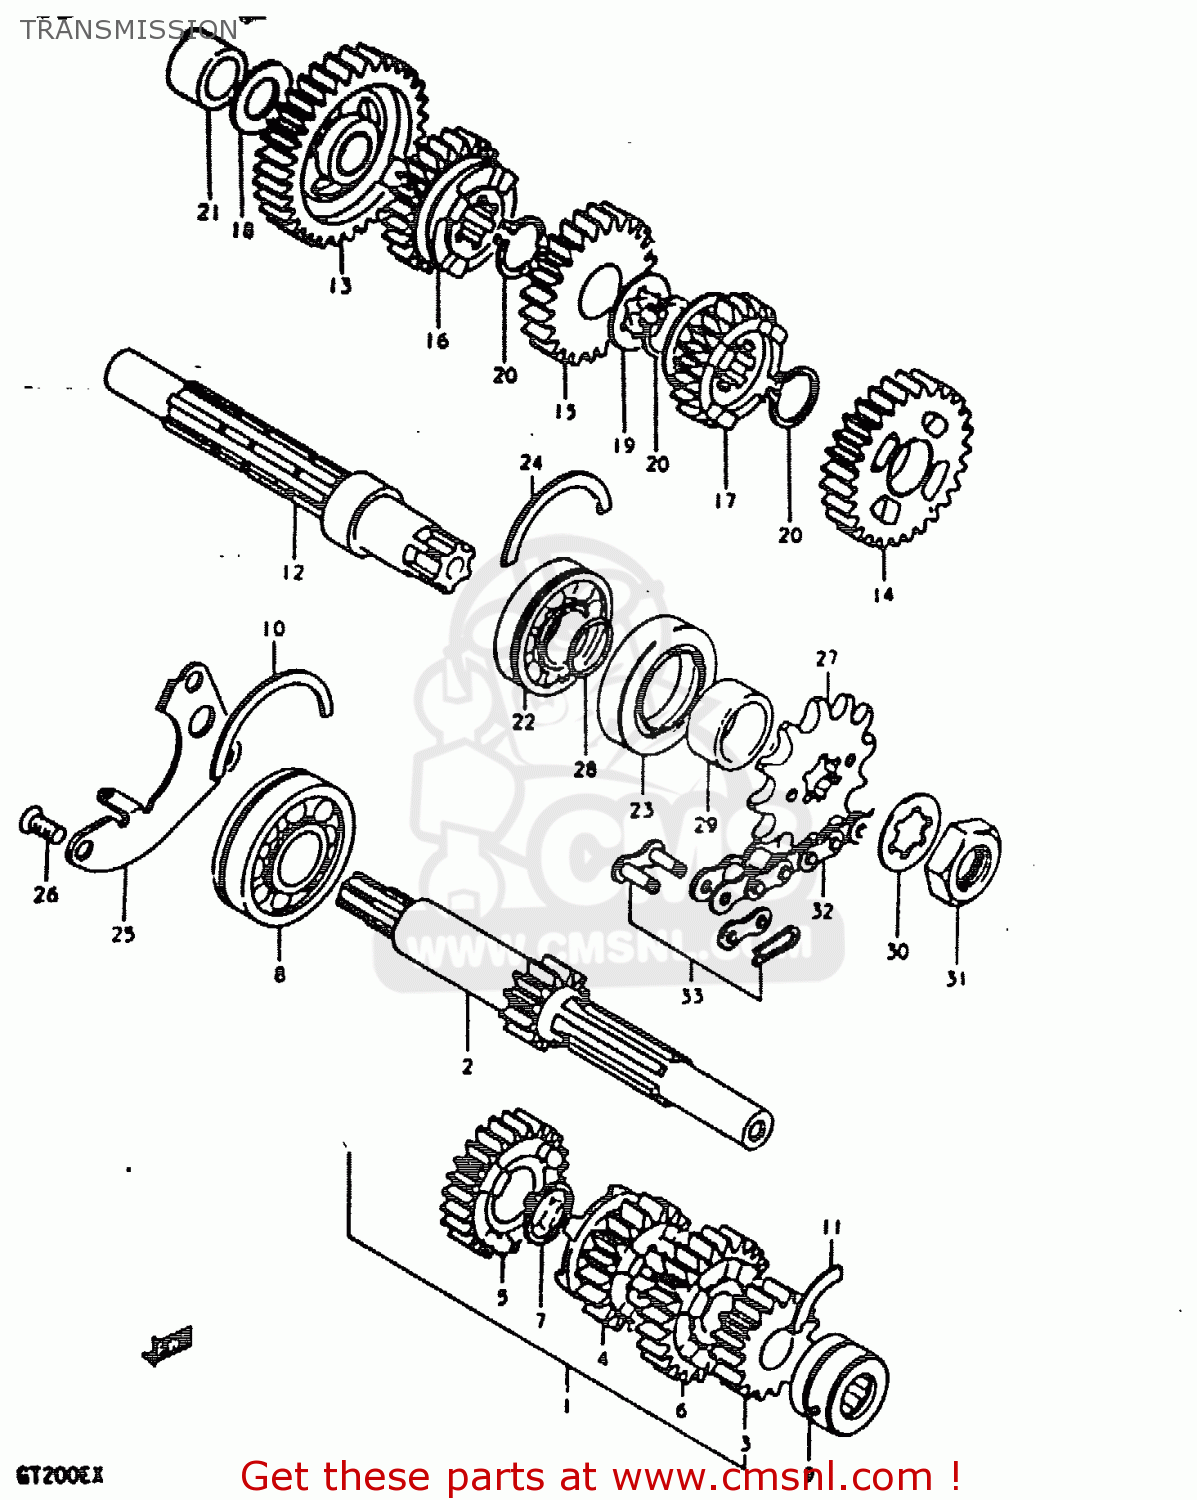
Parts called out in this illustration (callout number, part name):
1	COUNTERSHAFT ASSY
2	SHAFT, COUNTER
3	GEAR, 2ND DRIVE
4	GEAR, 3RD DRIVE
5	GEAR, 4TH DRIVE
6	GEAR, 5TH DRIVE
7	CIRCLIP
8	BEARING
9	ROLLER BEARING (15X30X1
10	C RING
11	KNOCK RING
12	SHAFT, DRIVE
13	GEAR, 1ST DRIVEN
14	GEAR, 2ND DRIVEN
15	GEAR, 3RD DRIVEN
16	GEAR, 4TH DRIVEN
17	GEAR, 5TH DRIVEN
18	THRUST WASHER
19	WASHER
20	CIRCLIP
21	BUSHING
22	BEARING(20X47X14)
23	OIL SEAL, LH
24	C RING
25	RETAINER
26	SCREW
27	SPROCKET,ENGINE
28	O RING(D:1,ID:19.5)
29	SPACER (20*26*17)
30	WASHER,LOCK
31	NUT
32	CHAIN ASSY, DRIVE
33	JOINT ASSEMBLY,CHAIN
